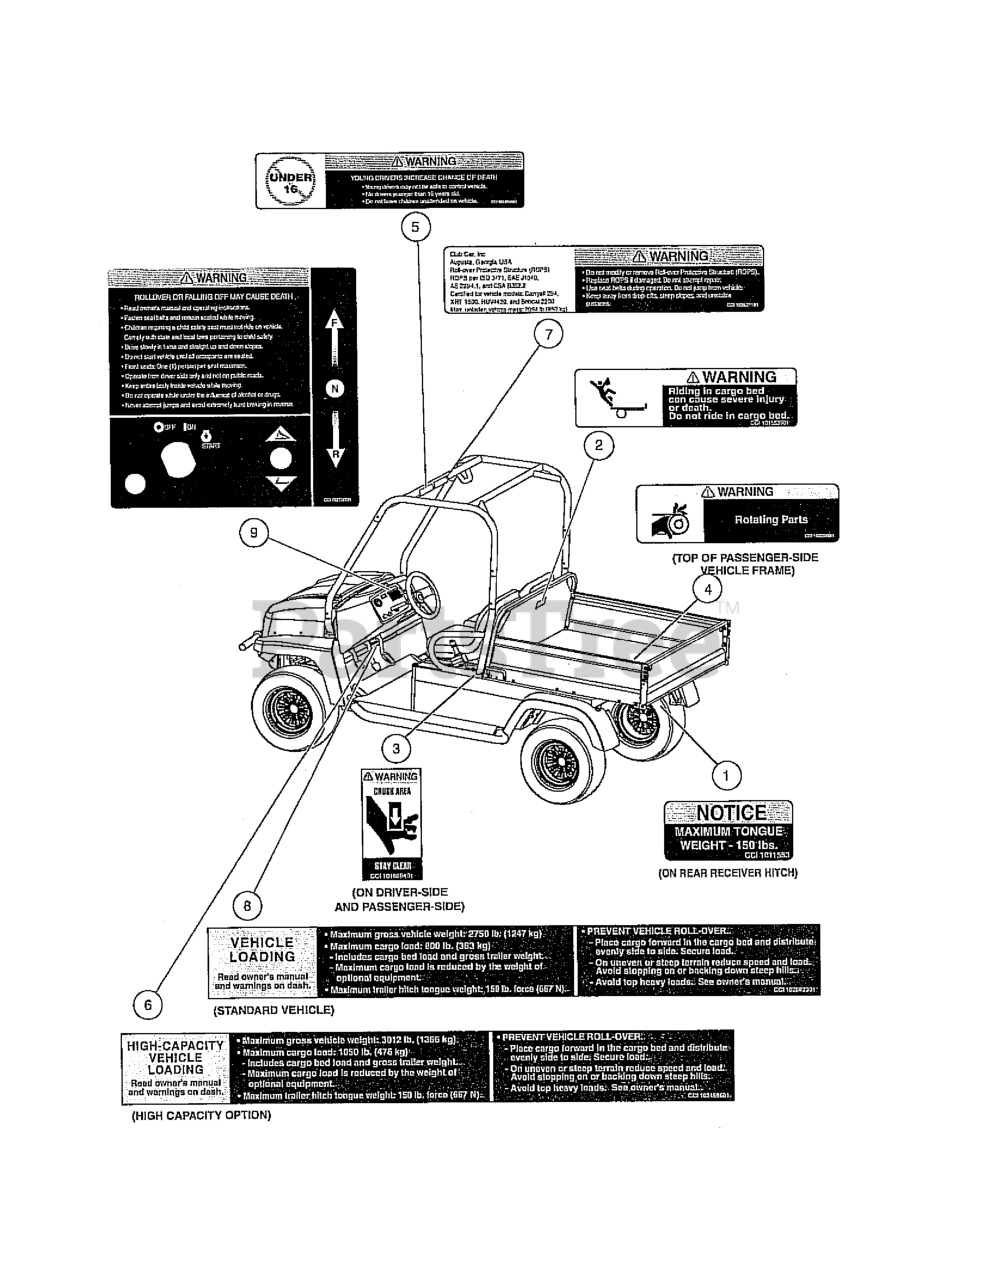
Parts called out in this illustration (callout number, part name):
1	DECAL, TRAILER HITCH
2	DECAL, BED LOAD WARNING
3	DECAL, CRUSH AREA WARNING
4	DECAL-ROTATING PARTS
5	DECAL, WARNING UNDER 16
6	DECAL, VEH LOAD HIGH CAPACITY
7	DECAL, WARNING-CERTIFIED ROPS
8	DECAL, VEHICLE LOAD, 2750 LBS
9	DECAL-WARNING-GAS
